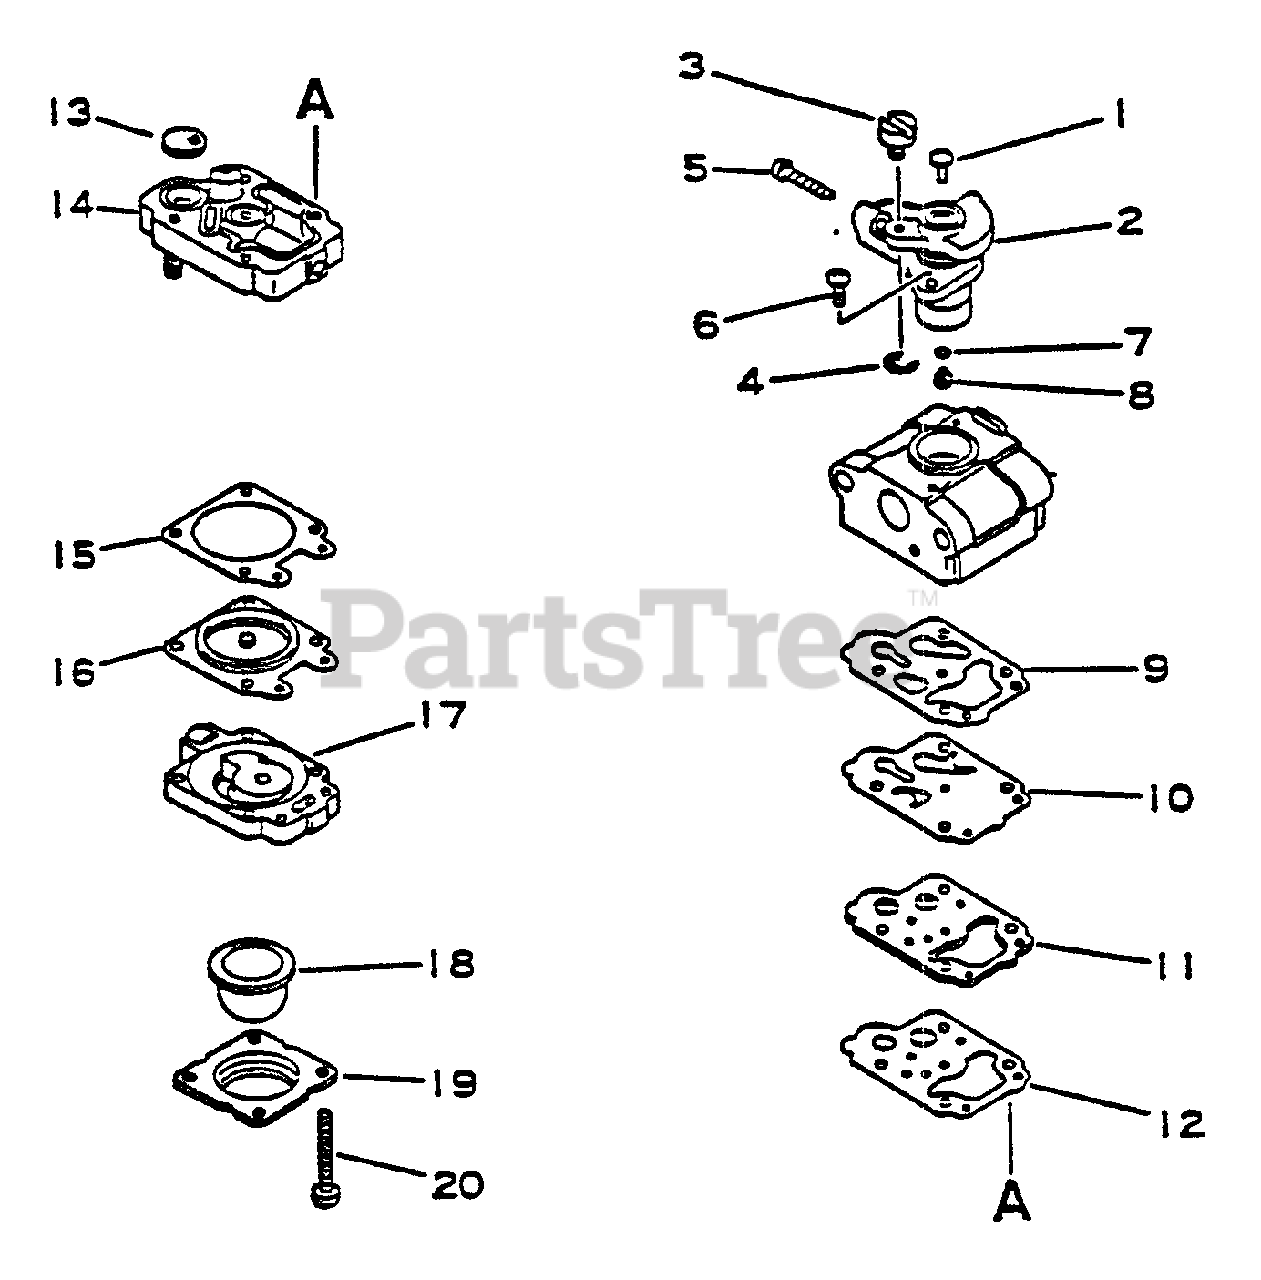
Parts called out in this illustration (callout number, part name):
1	PLUG, WELCH
2	THROTTLE VALVE ASSY
4	RING, RETAINING
5	SCREW, IDLE ADJUST
7	O-RING
8	JET
9	GASKET, PURGE
10	DIAPHRAGM, PURGE
11	PLATE, PUMP
12	GASKET, PLATE
13	STRAINER
14	BASE, PURGE
15	GASKET, METERING
16	DIAPHRAGM, METERING
17	BASE, PURGE
18	BULB, PURGE
19	RETAINER, PURGE BULB
